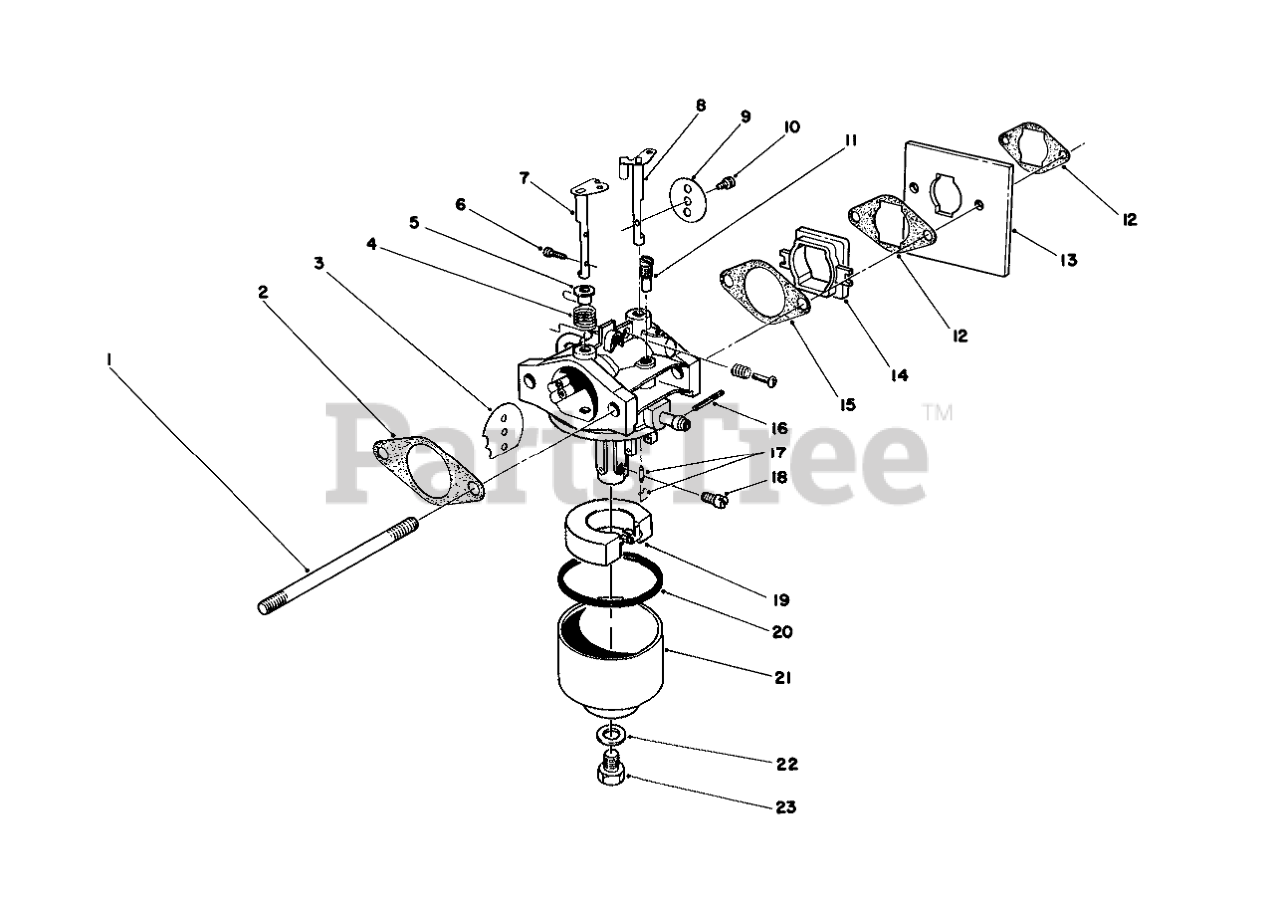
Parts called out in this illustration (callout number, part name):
1	CARB STUD BOLT
2	GASKET-AIR CLEANER
3	PLATE
4	SPRING
5	BUSHING
6	SCREW
7	SHAFT-CHOKE
8	SHAFT
9	PLATE
10	Screw-Throttle
11	PILOT JET
12	GASKET
13	SHIELD
14	INSULATOR
15	GASKET-CARB
16	Pin
17	NEEDLE VALVE ASM
18	MAIN JET (76.3)
19	FLOAT
20	GASKET
21	Bowl-Float
22	GASKET
23	Bolt
